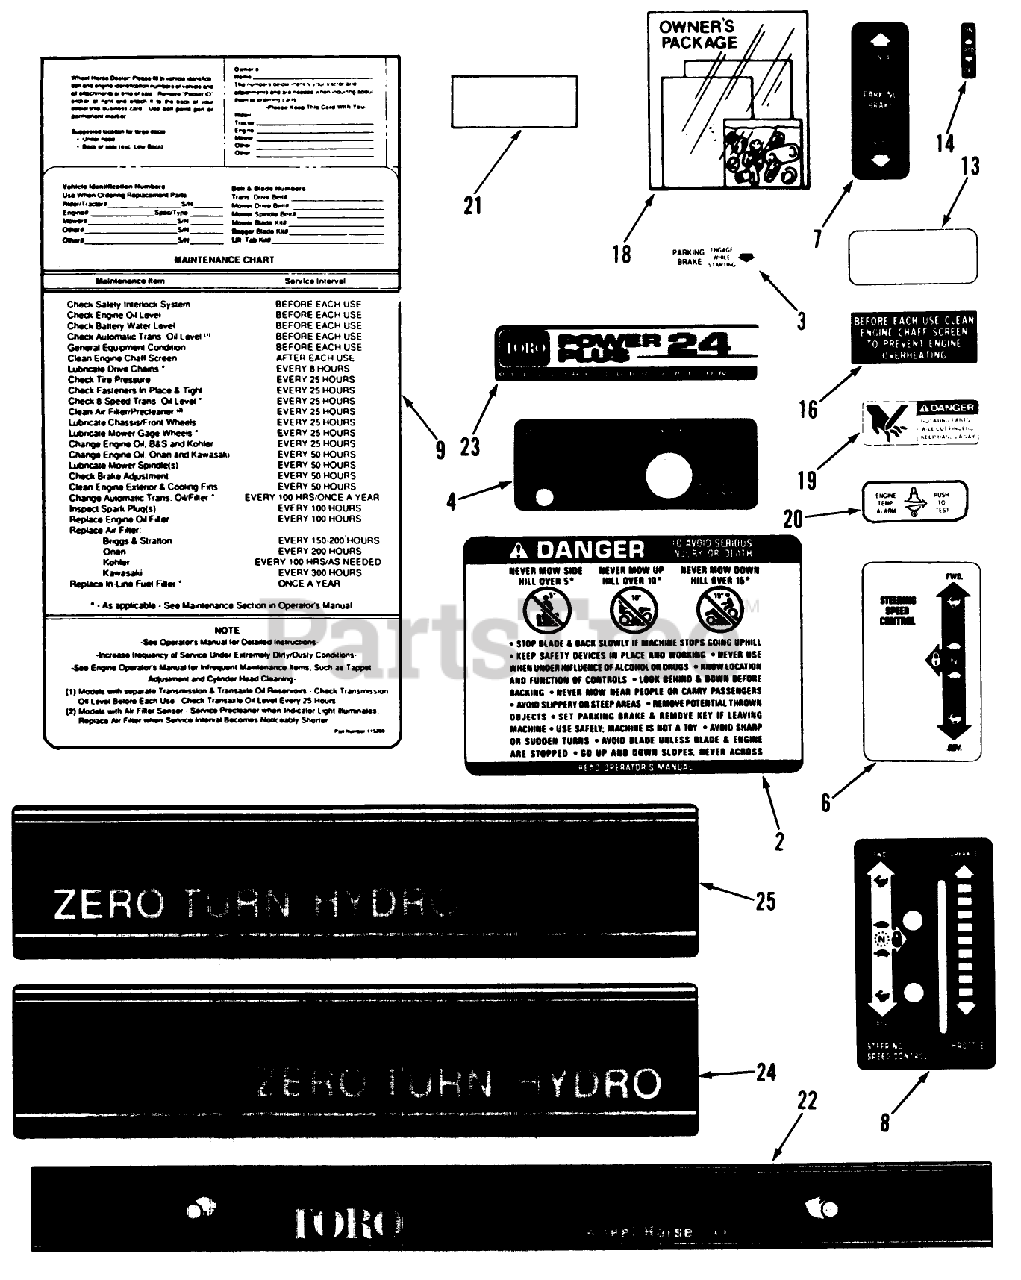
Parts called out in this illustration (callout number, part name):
2	DECAL-DANGER
3	Decal-Parking Brake
4	DECAL-CHOKE/IGNITION
6	Decal-SpeedControl
7	Decal-Parking Brake
8	DECAL-STRG THROTTLE
9	MAINTENANCE-DECAL
13	DECAL-OVERLAY
14	DECAL-PTO
16	DECAL-ENGINE SCREEN
18	Loose Parts Package-New Tractor
19	DECAL-DANGER
20	Decal-Temperature Alarm
21	DECAL-ENGINE SCREEN
22	Decal-Hood
23	DECAL-PWR PLUS 24 PL
24	DECAL-ZERO TURN R.H.
25	DECAL-ZERO TURN L.H.
